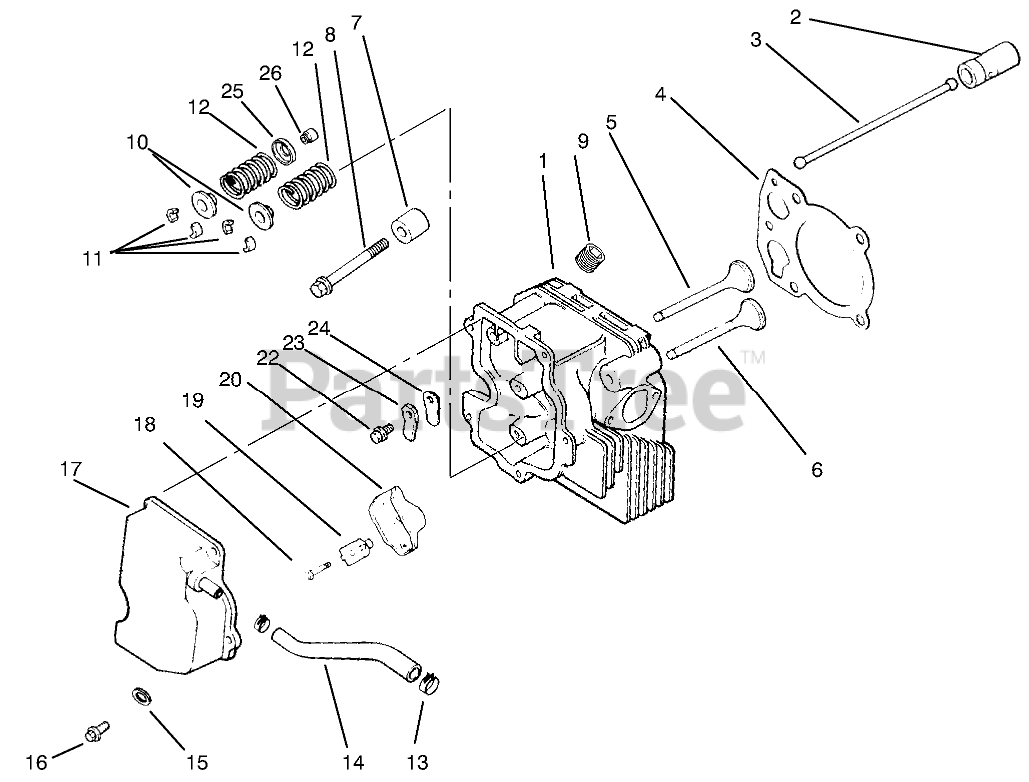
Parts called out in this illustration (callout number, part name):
1	Cylinder Head
2	Lifter-Valve
3	Rod-Push
4	Gasket-Cylinder Head
5	Valve-Intake STD
5	Valve-Intake .25
6	Valve-Exhaust STD
6	Valve-Exhaust .25
7	Spacer-Head Bolt Exhaust
8	Screw M10x1.5x80
9	Plug
10	Cap-Valve Spring
11	Kit-Retainer
12	Spring-Valve
13	Clamp
14	Hose-Breather
15	Washer-Flat
16	Screw
17	Cover-Valve w/Nipple
19	Pivot-Rocket Arm
20	Arm-Rocker
22	Screw
23	Retainer-Breather Reed
24	Reed-Breather
25	Retainer-Spring
26	Seal-Valve Stem
